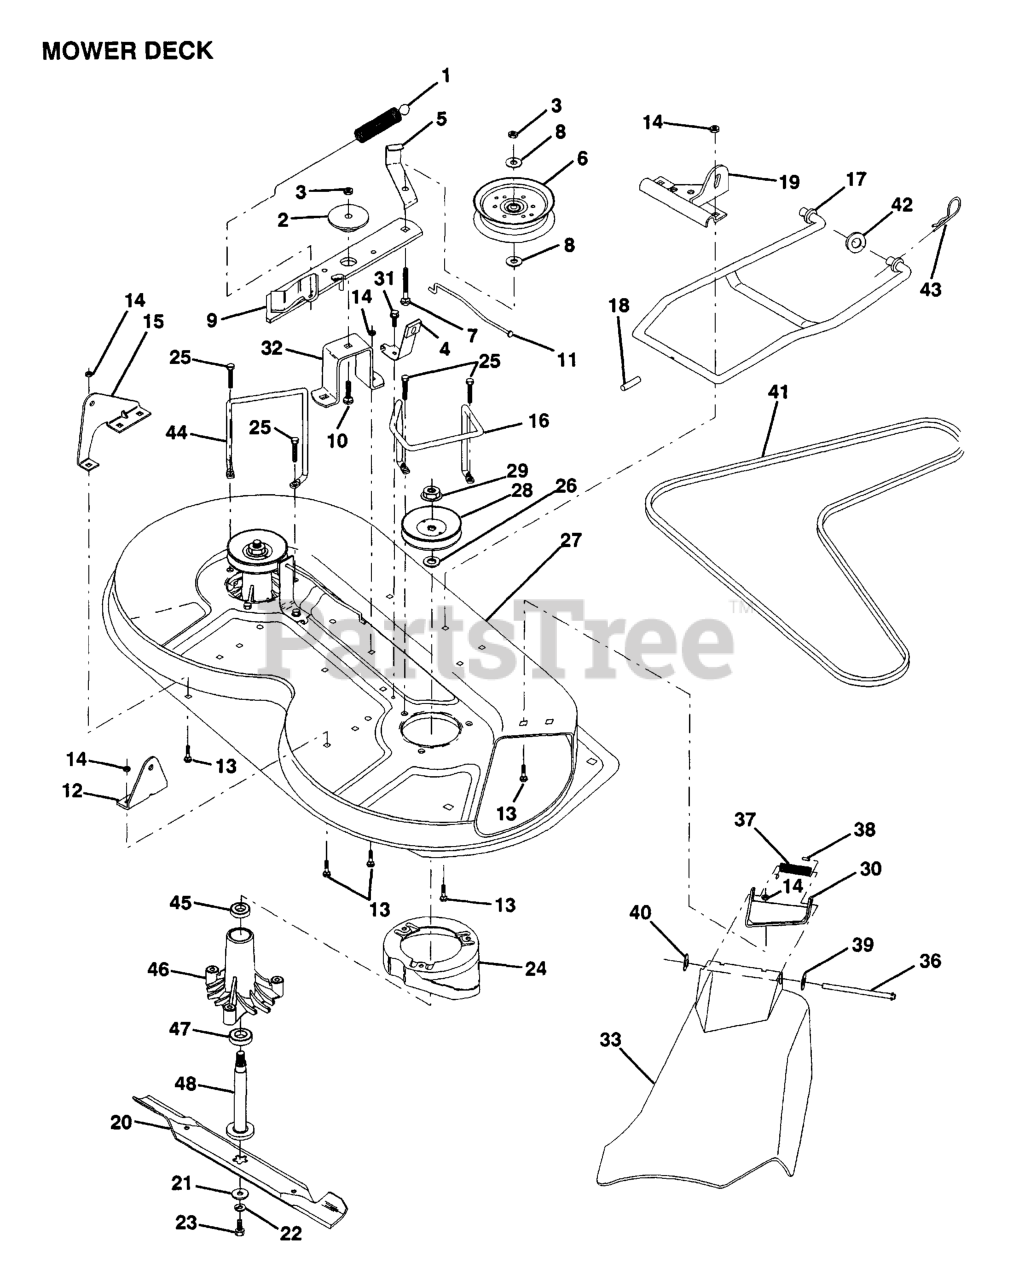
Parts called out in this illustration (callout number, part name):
1	SPRING
2	SPACER RETAINER
4	BRAKE ASSEMBLY
5	IDLER BELT GUIDE
6	PULLEY.IDLER.FLAT.MOWER.BLK.PT
8	WASHER CRT
9	IDLER ARM ASSY
10	BOLT D
12	BRKT LIFT REAR
13	BOLT
14	LOCKNUT
15	BRKT,REAR LIFT LH
16	KEEPER RH
17	MOWER LINK STABILIZER
18	PIN GROOVE
19	BRKT LINK STABILIIZER
20	BLADE
21	WASHER
22	WASHER, LOCK 3/8
23	BLADE BOLT
24	STRIPPER
25	BOLT, HEX 5/16-18X1-3/4
26	WASHER
27	MOWER HOUSING
28	PULLEY
29	NUT FLANGELOCK 9/16
30	BRKT,DEFLECTOR
31	Screw 5/16-18 x 1/2 Hex, Self Tapping 5/16-18 x 1/2
32	SUPT,IDLER ARM
33	DEFLECTOR
36	HINGE ROD
37	SPRING TORSION
38	CAP-SLEEVE LT
39	WASHER
40	NUT PUSH M
42	WASHER
43	SPRING RETAINER
44	KEEPER LH
46	HOUSING.MANDREL.VENTED (MACHD)
47	BEARING.BALL.#6204.(MANDREL)
48	SHAFT MANDREL (INCL KEY #47)
